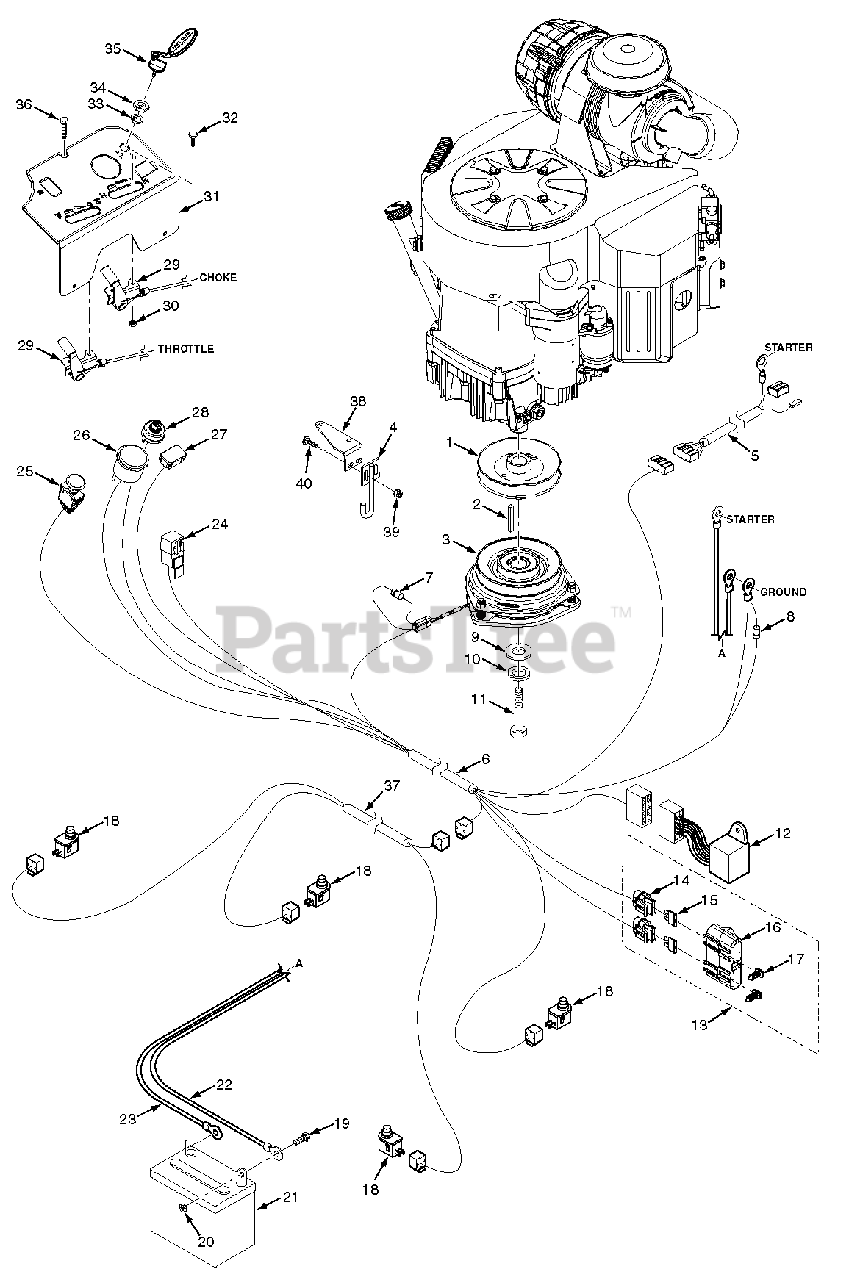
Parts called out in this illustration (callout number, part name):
1	Pulley, 5.80 Dia. - 1.125 Bore
2	Key, 1/4 x 1/4 x 3-1/4"
3	Electric Clutch w/Tag (GT-3.5)
3	Electric Clutch w/Tag (GT-5)
4	Weldment, Anti-Rotation
5	Wire Harness Adapter
6	Wire Harness, SCZ
7	Diode, 600V - 6A
8	Diode
9	Flatwasher, 7/16-.469 x 1.75 x .25
10	Lockwasher, 7/16" Spring
11	Bolt, Hex Head 7/16-20 x 2-1/4" w/Patch
11	Bolt, Hex Head
12	Electric Module
13	Double Fuse Assembky
14	Fuse Holder
15	Fuse, 20 Amp
16	Cover, Sealed Double
17	Clip, Wire
18	Switch, N.O.
19	Bolt, Hex Head 1/4-20 x 1/2"
20	Nut, 1/4-20
21	Battery
22	Battery Cable, 27" Black
22	Battery Cable, 18" Black
23	Battery Cable, 25" Red
24	Relay
25	Switch, PTO - 10 Amp
26	Ammeter
27	Hourmeter
28	Keyswitch w/Hardware
29	Control Cable
30	Nut, Elastic Stop #10-24
31	Instrument Panel w/Decal
32	Bolt, Carriage #10-24 x 1/2"
33	Lockwasher, 5/8" Internal
34	Nut, Hex 5/8-32
35	Key, Ignition
36	Bolt, Hex Head 1/4-20 x 1/2" Serrated Flange
37	Wire Harness, Operator Platform - SCZ
38	Bracket, Anti-Rotation
39	Nut, FLF HH Elastic Stop 5/16-18
40	Bolt, Carriage 5/16-18 x 1"
